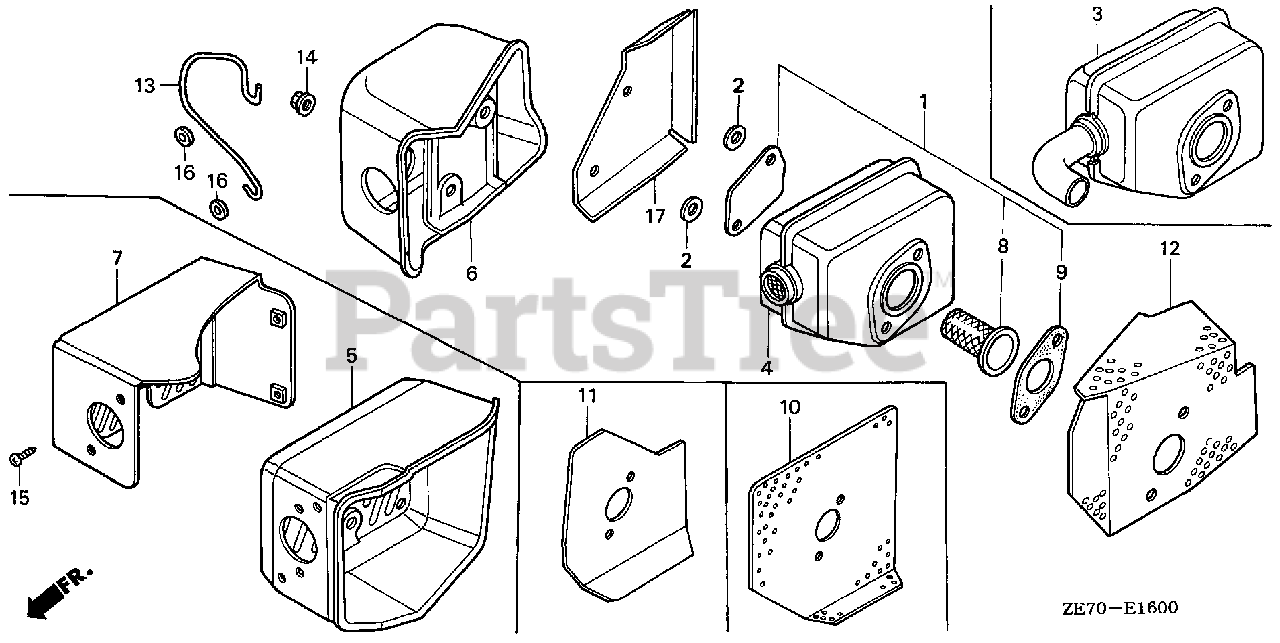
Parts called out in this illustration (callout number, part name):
1	ARRESTER KIT, SPARK
4	MUFFLER
5	PROTECTOR, MUFFLER
8	ARRESTER KIT, SPARK
10	GASKET, MUFFLER
14	NUT, SELF-LOCK (6MM)
